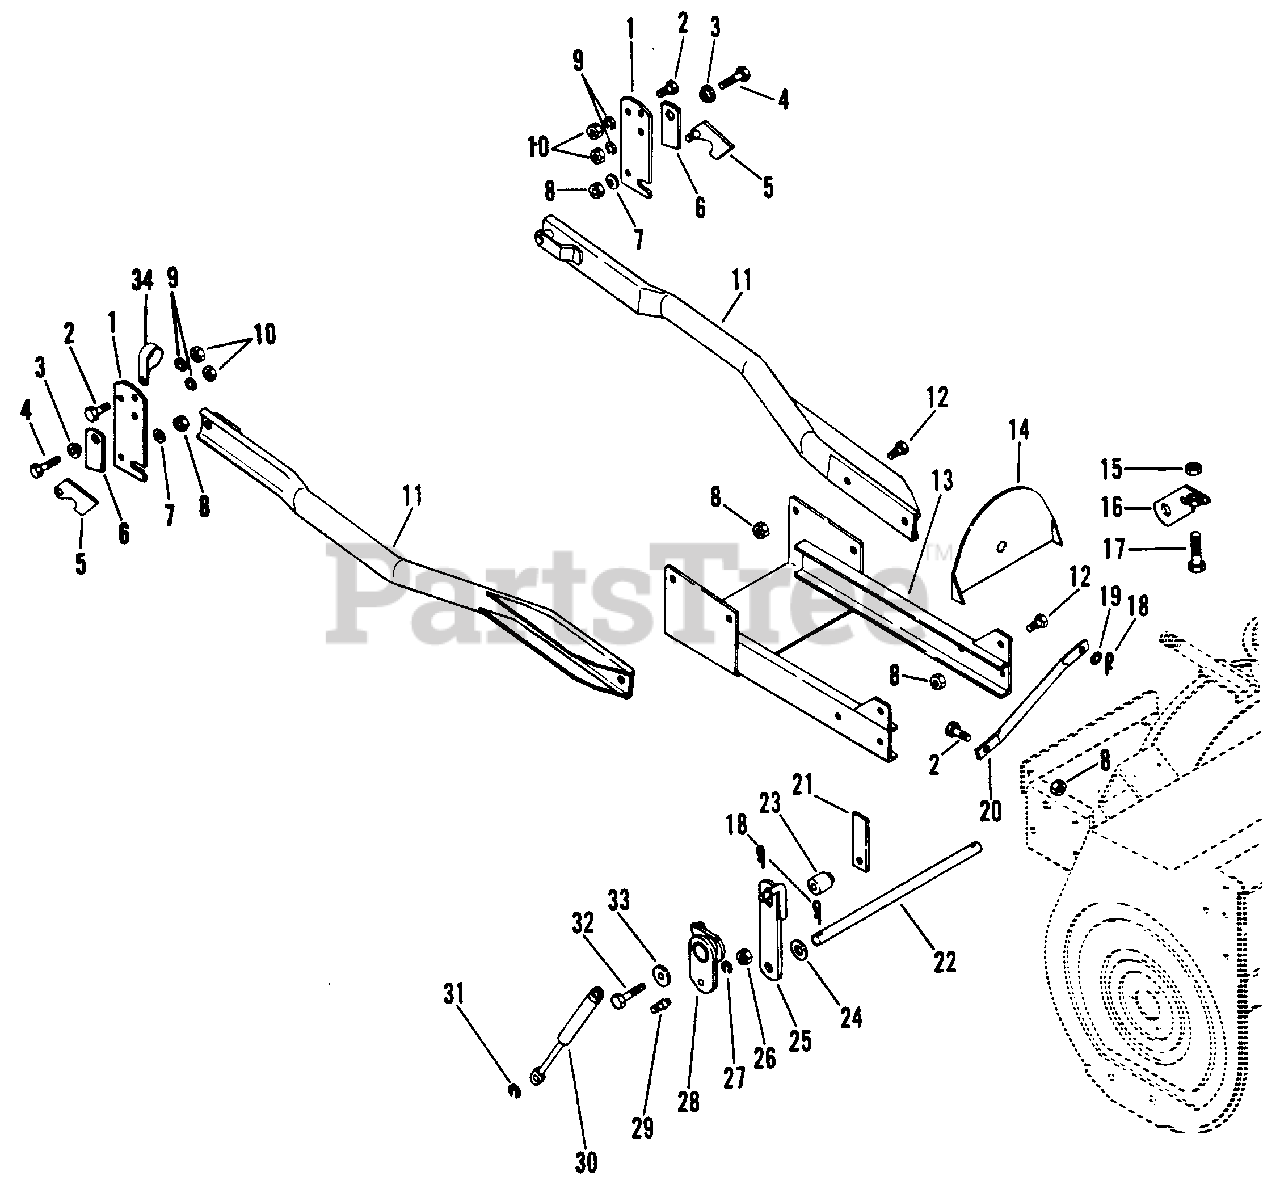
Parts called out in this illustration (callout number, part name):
1	Rear Hanger Bracket
2	Bolt, Hex 3/8-16x1.00
3	Spacer
4	Bolt, Hex 3/8-16x1.50
5	R.H. Latch
5	L.H. Latch
6	Lock, Stop
7	Spring Washer
8	Nut, Lock 3/8-16
9	Washer, Lock 3/8 Reg.
10	Nut, Hex 3/8-16
11	Rear Attachment Brace
12	Bolt, Hex 3/8-16x.75
13	Channel Cross
14	Shield
15	Nut, Hex 1/2-13
16	Adjustment Link
17	Bolt, Hex 1/2-13x2.00
18	Hair Pin 2/32X1-7/8
19	Washer 3/8
20	Stabilizer
21	Bolt Plate
22	Pivot Rod
23	Pivot
24	Washer, Flat .656x1.312x.095
25	R.H. Lift Link
25	L.H. Lift Link
26	Nut, Jam 5/16-18 Hex
27	Washer, Lock 5/16 Reg.
28	R.H. Lift Assist Bracket
28	L.H. Lift Assist Bracket
29	Stud
30	Lift Assist Cylinder
31	E-Ring Extension
32	Bolt, Hex 3/8-16x2.00
33	Washer .401/.421x1.125x.125
34	Clamp
